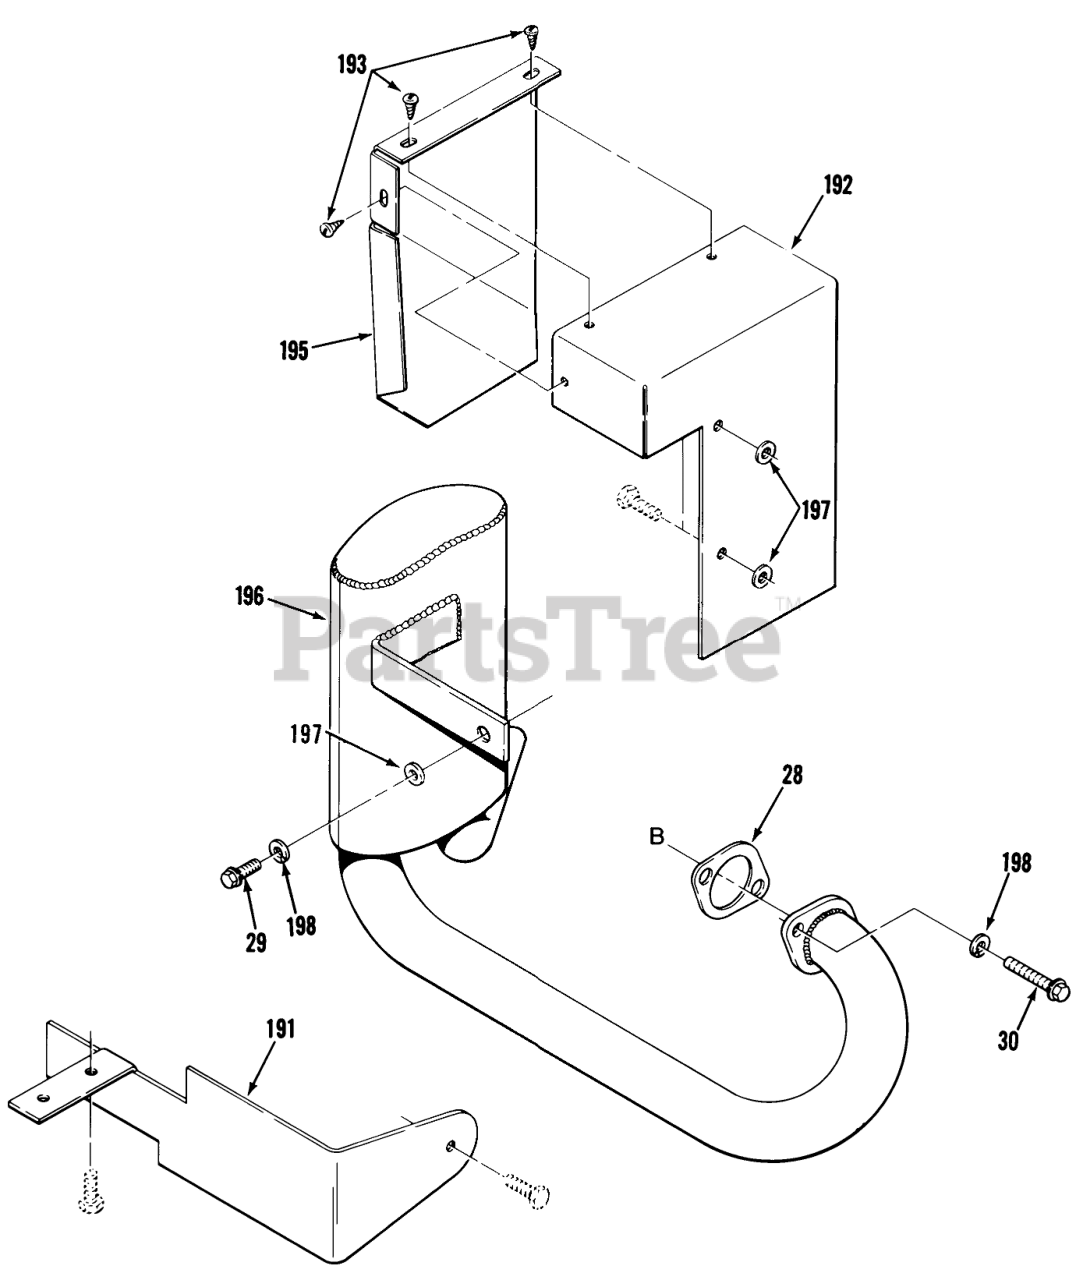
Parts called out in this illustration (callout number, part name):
28	GASKET
29	BOLT-FLANGED
30	BOLT-FLANGED
191	DEFLECTOR-FRONT B
192	SHIELD-HEAT B
193	SCRW-HX S.T.#8 X 3/8
195	SHIELD-HEAT
196	Muffler-Black
197	WASHER 5/16 SAE
198	Lockwasher
